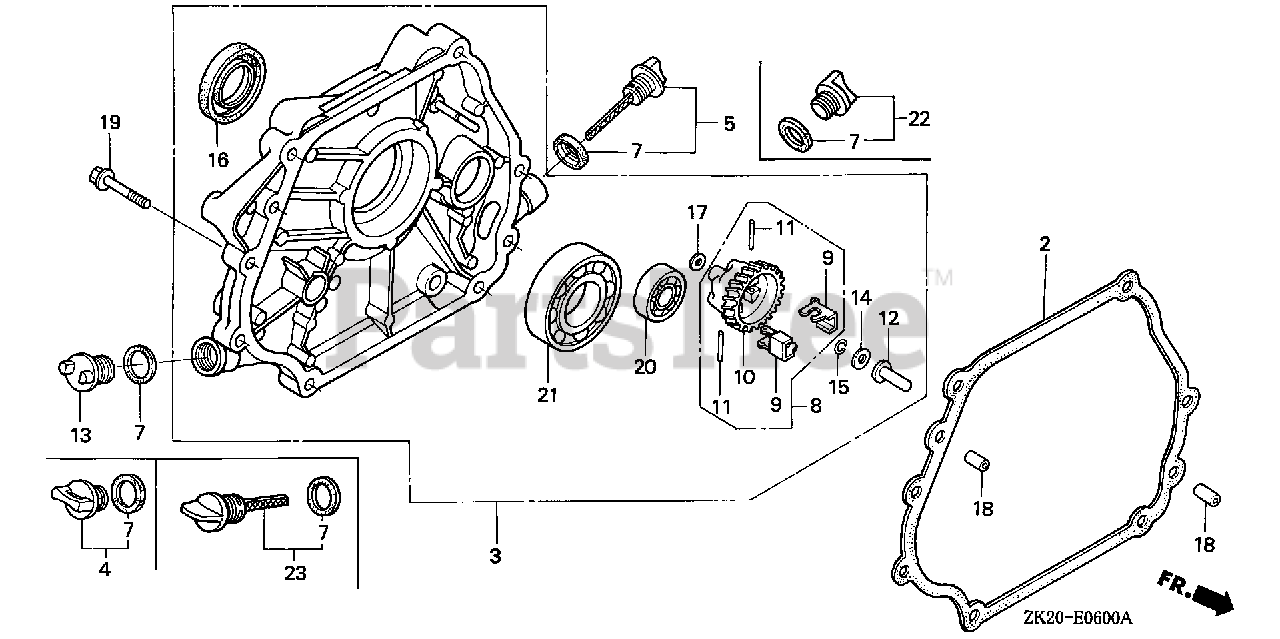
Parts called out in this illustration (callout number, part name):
2	GASKET, CASE COVER
3	COVER ASSY., CRANKCASE
4	CAP ASSY., OIL FILLER
5	CAP ASSY., OIL FILLER
7	GASKET, OIL FILLER CAP
8	GOVERNOR ASSY.
9	WEIGHT, GOVERNOR
10	HOLDER, GOVERNOR WEIGHT
11	PIN, GOVERNOR WEIGHT
12	SLIDER, GOVERNOR
13	CAP, OIL FILLER
14	WASHER (6X16)
15	CLIP, GOVERNOR HOLDER
16	OIL SEAL (30X46X8)
17	WASHER, PLAIN (6MM)
18	PIN, DOWEL (8X12)
19	BOLT, FLANGE (8X35)
20	BEARING, RADIAL BALL (6202)
21	BEARING, RADIAL BALL (6206)
